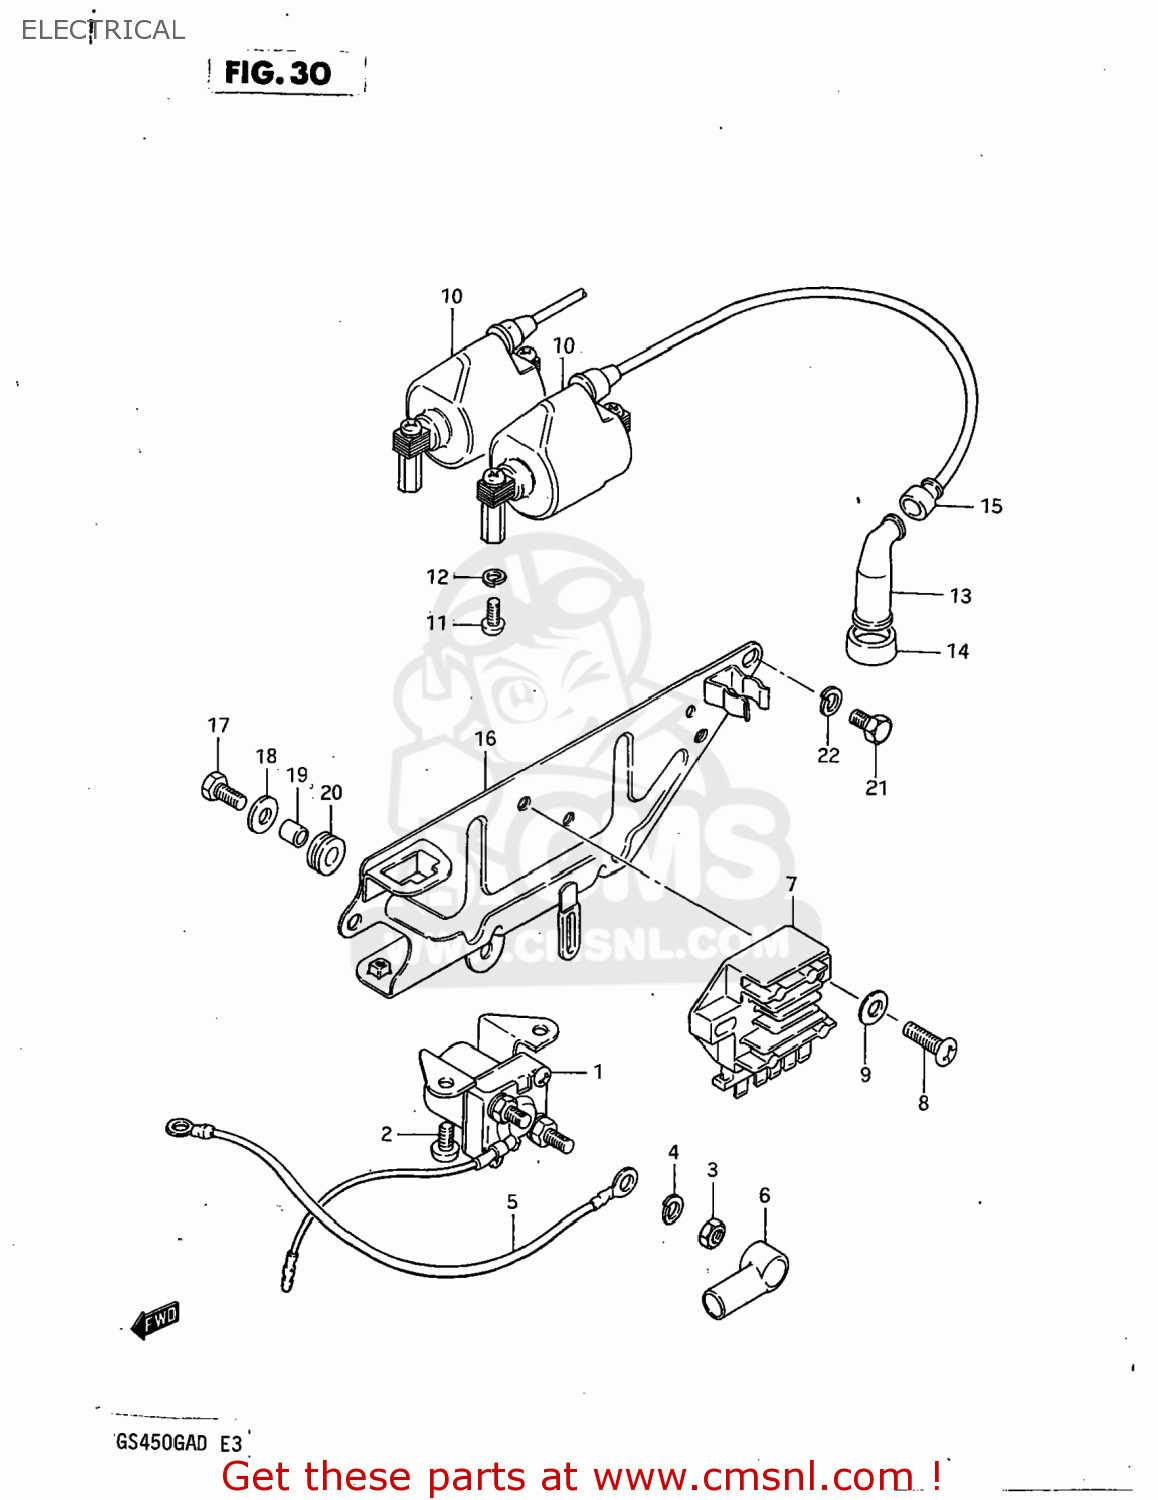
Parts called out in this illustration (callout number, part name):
1	RELAY,STARTER SWITCH
2	SCREW
3	NUT 6MM
4	LOCK WASHER
5	CORD,BATTERY MINUS
6	CAP,STARTER RELAY
7	RECTIFIER ASSEMBLY
8	SCREW
9	WASHER
10	COIL ASSEMBLY,IGNITION
11	SCREW
12	LOCK WASHER
13	CAP,SPARK PLUG
14	SEAL,SPARK PLUG
15	SEAL,SPARK PLU
16	HOLDER COMP,ELECTRONIC PARTS
17	BOLT
18	WASHER
19	SPACER (6.1X8X9.5)
20	CUSHION
21	BOLT
22	LOCK WASHER
